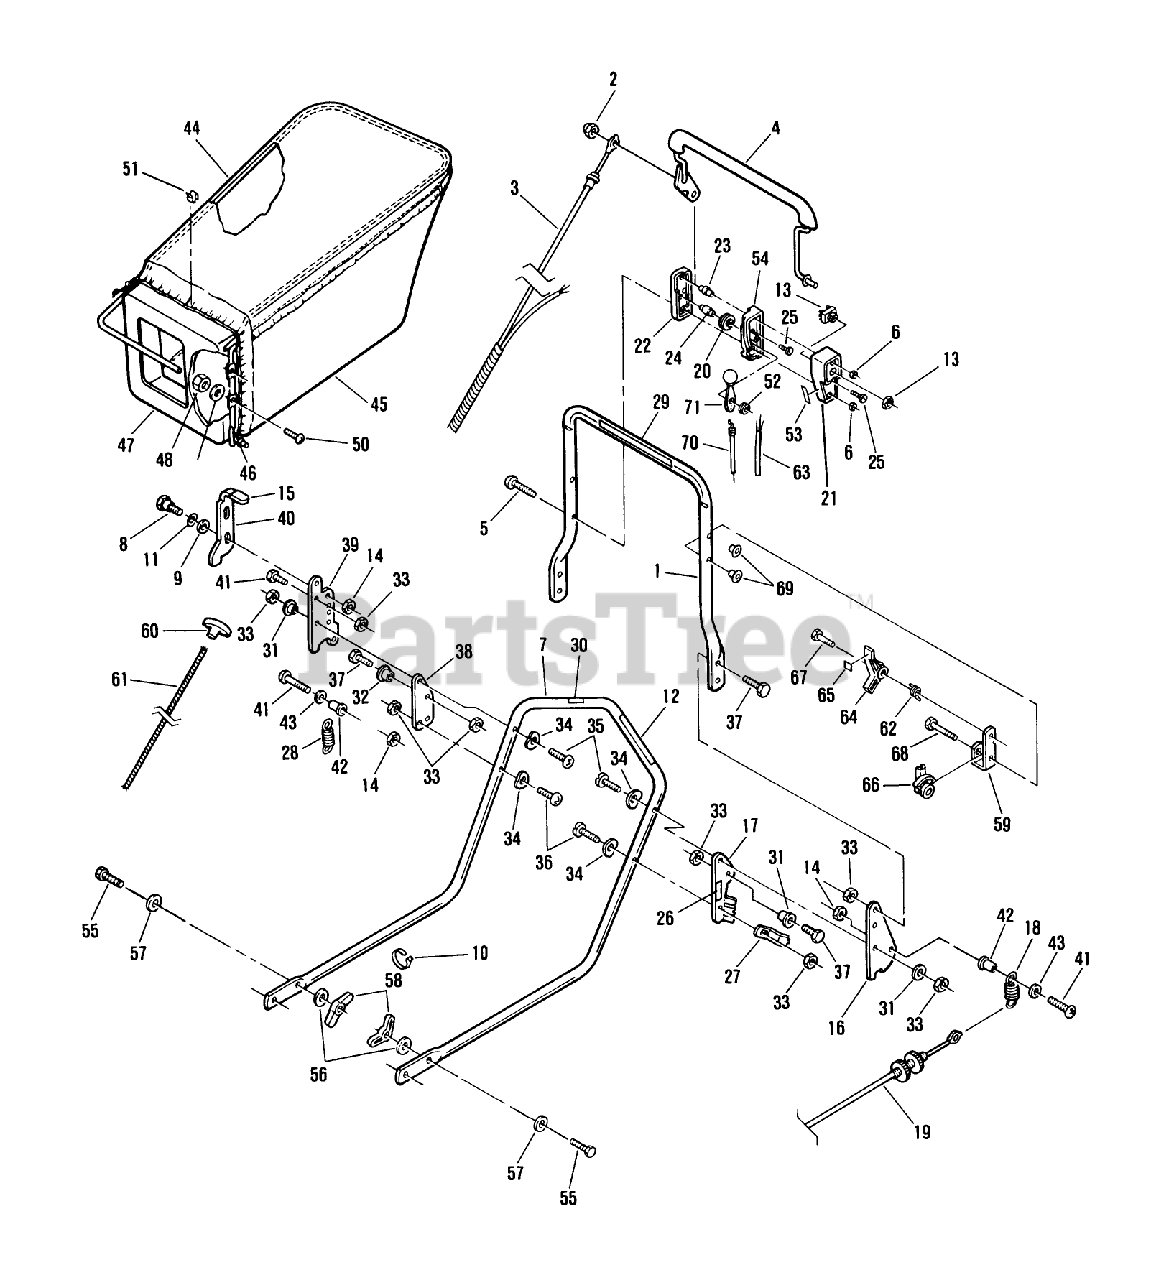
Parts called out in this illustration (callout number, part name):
2	NUT ACORN
3	CONTROL CABLE WES
5	SCREW
6	NUT C/LOCK E
8	BOLT RB&W
9	WASHER M
14	LOCKNUT E
15	KNOB (S&R)
18	SPRING
19	CABLE AY
20	PULLEY PL
23	COLUMN
24	PIN SKF
25	SCREW
33	NUT-LOCK F
34	WASHER-CURVED
35	SCREW LARSON
42	SPACER ROCKFORD
43	WASHER
44	HANGER BAG TROX
47	BAG ADAPTOR PL
48	LOCKNUT E
49	WASHER
51	S CLIP ARDEN
52	WASHER-SPRING
57	WASHER
58	NUT-WING
68	BOLT QUALITY
70	CABLE TH'TTLE WES
71	LEVER&KNOB AY WES
